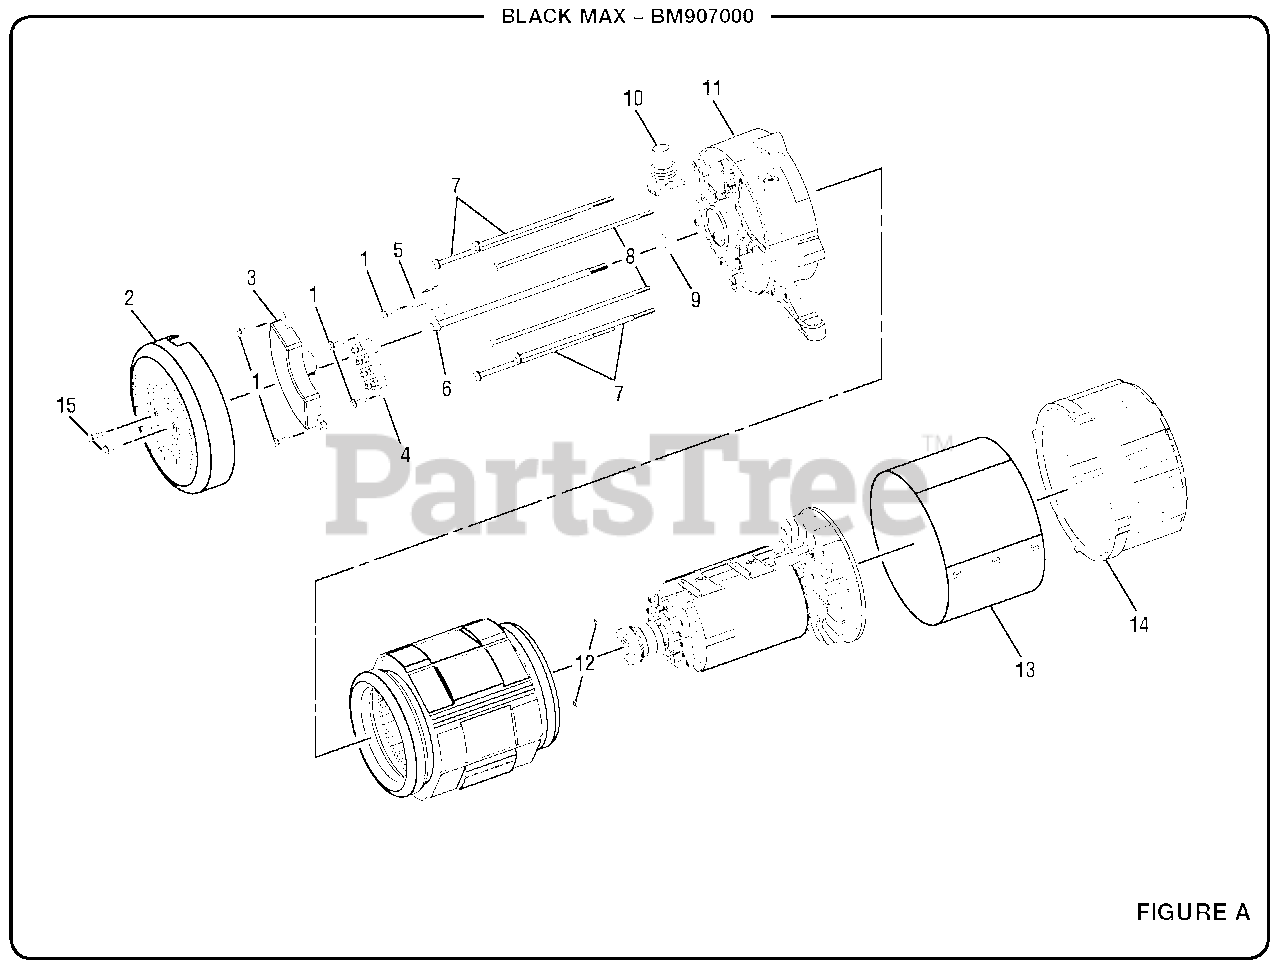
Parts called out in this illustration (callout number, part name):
1	Bolt (M5 x 16 mm, Hex Hd.)
2	Brush Cover
3	Automatic Voltage Regulator
4	Terminal Block
5	Brush Assembly
6	Bolt (5/16-24 x 235 mm, Hex Washer Hd.)
7	Bolt (M6 x 188 mm, Hex Washer Hd.)
8	Bolt (M5 x 210 mm, Hex Washer Hd.)
9	Washer (8 x 26 x 3t)
10	Rubber Boot
11	Bearing Housing
12	Hex Nut (M5)
13	Generator Head Cover
14	Adaptor Housing
15	Bolt (M5 x 12 mm, Hex Hd.)
